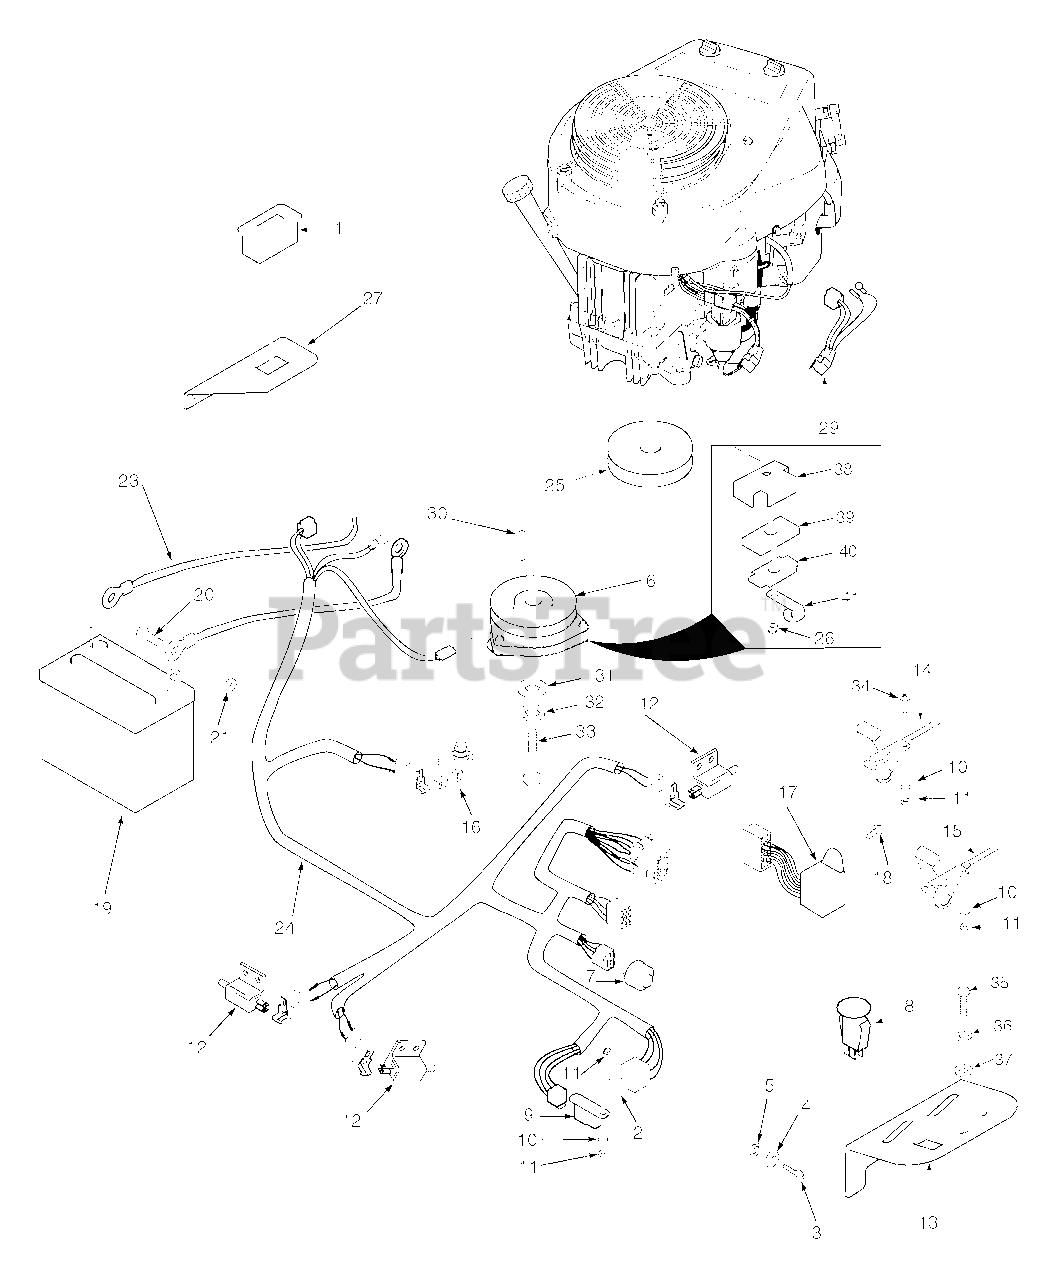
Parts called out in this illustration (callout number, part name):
1	Hourmeter
2	Fuse, 20 amp
3	Key, Ignition
4	Nut, Hex 5/8-32
5	Lockwasher, 5/8" Internal
6	Electric PTO Clutch GT3.5
7	Switch, Ignition
8	Switch, PTO
9	Relay
10	Lock Washer, #10 External Tooth
11	Nut, Hex #10-32
12	Switch, N/O
13	Panel, Instrument
14	Choke & Throttle Control - Kawasaki (Qty 2)
15	Throttle Control - Kohler ( Qty 1)
16	Switch, Seat
17	Module, Interlock
18	Screw, #10-32 x .5" Phillips Head
19	Battery
20	Bolt, Hex Head 1/4-20 x .5"
21	Nut, Hex 1/4-20
22	Cable, Battery Black (negative)
23	Cable, Battery Red (positive)
24	Wiring Harness, Main
25	Pulley, 5.45 OD x 1.125 Bore
26	Nut, Elastic Stop 5/16-18 Key
27	Mounting Bracket, Hour Meter
28	Screw, #10-32 x 1.5" Phillips Head
29	Adaptor, Wiring Harness (Kawasaki only)
30	Key, 1/4 x 1/4 x 3-1/4"
31	Flatwasher, 7/16-.469 x 1-3/4" x 1/4"
32	Lockwasher, 7/16"
33	Bolt, Hex Head 7/16-20 x 2-1/2" UNF
34	Screw, #10-32 x 3/4"
35	Bolt, Hex Head 5/16-18 x 3/4"
36	Lockwasher, 5/16
37	Flatwasher, 5/16-.375 x .875 x .083
38	Backing Plate
39	Rubber Pad, Clutch Stop
40	Plate, Backing
